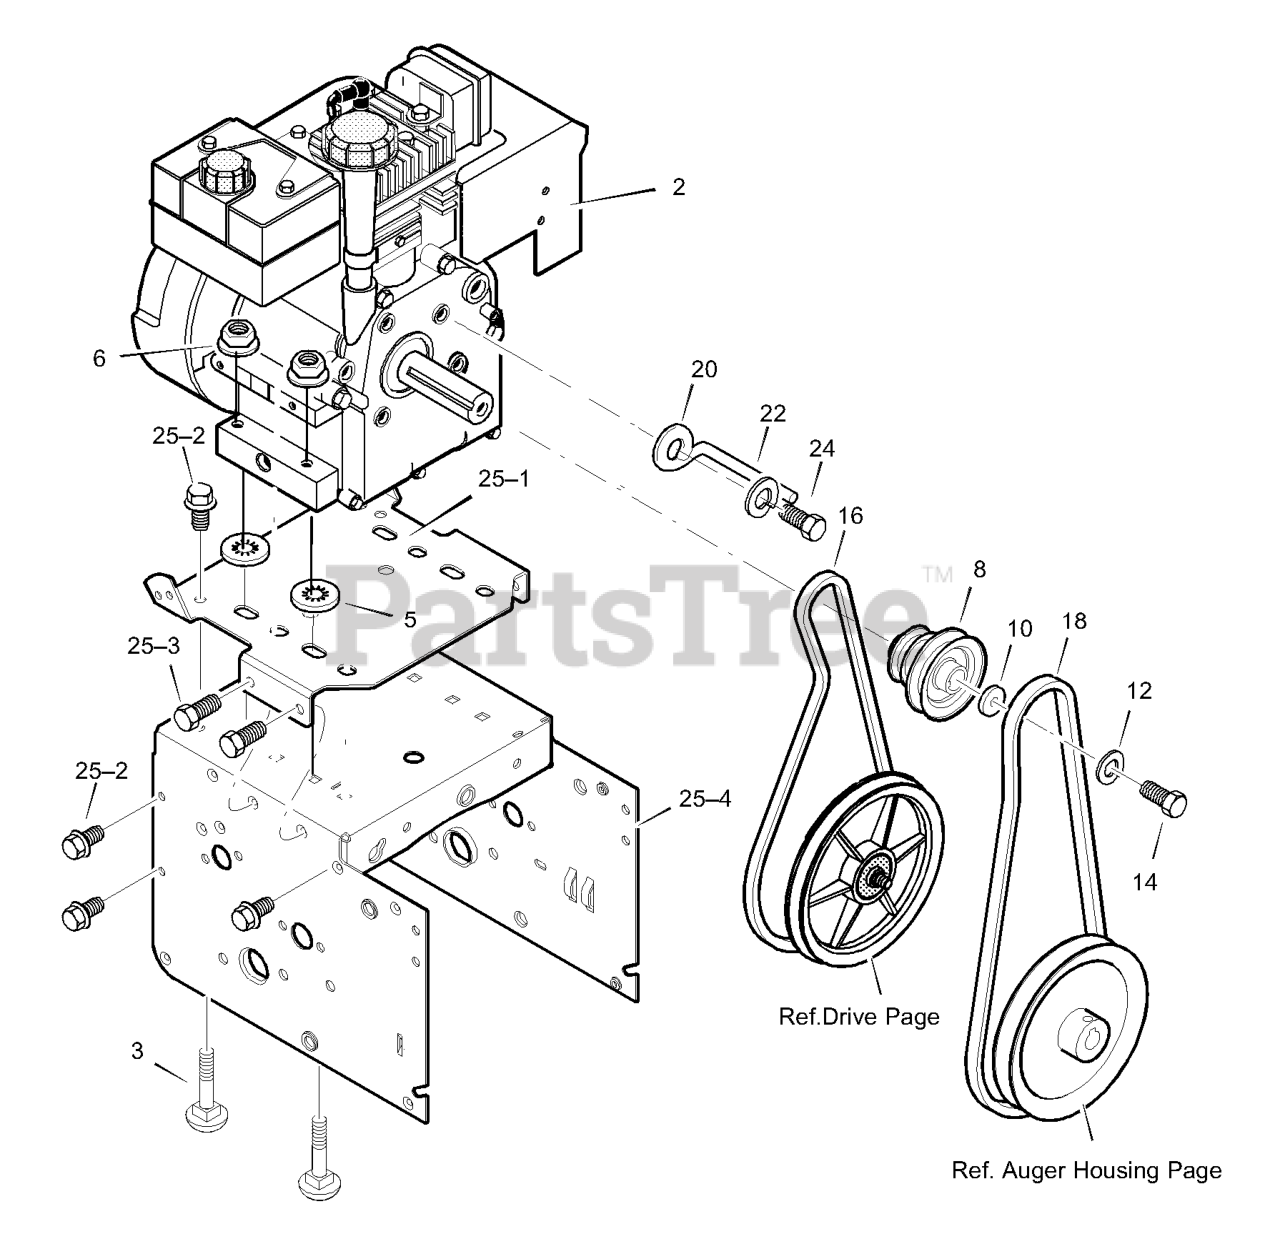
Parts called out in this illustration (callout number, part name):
2	ENGINE
3	BOLT, CARRIAGE 5/16-18
5	RETAINER, PUSH
6	NUT, HEX 5/16-18
8	PULLEY, ENGINE
10	WASHER
12	WASHER .38ID
14	SCREW, 3/8-24 x 1.00
16	BELT, V 3L 33.13LG
18	BELT, V 4L 38.1MF16" 5-10
20	GUIDE, BELT
22	WASHER, SPTLK .31 X .58X.08
24	SCREW, 5/16-24 x 0.75
25	FRAME ASSEMBLY
25-1	PLATE, ENGINE MOUNT
25-2	SCREW, TAP 1/4-20 X .63
25-3	SCREW, TAP 5/16-18 X .50
25-4	FRAME, MOTOR BOX
